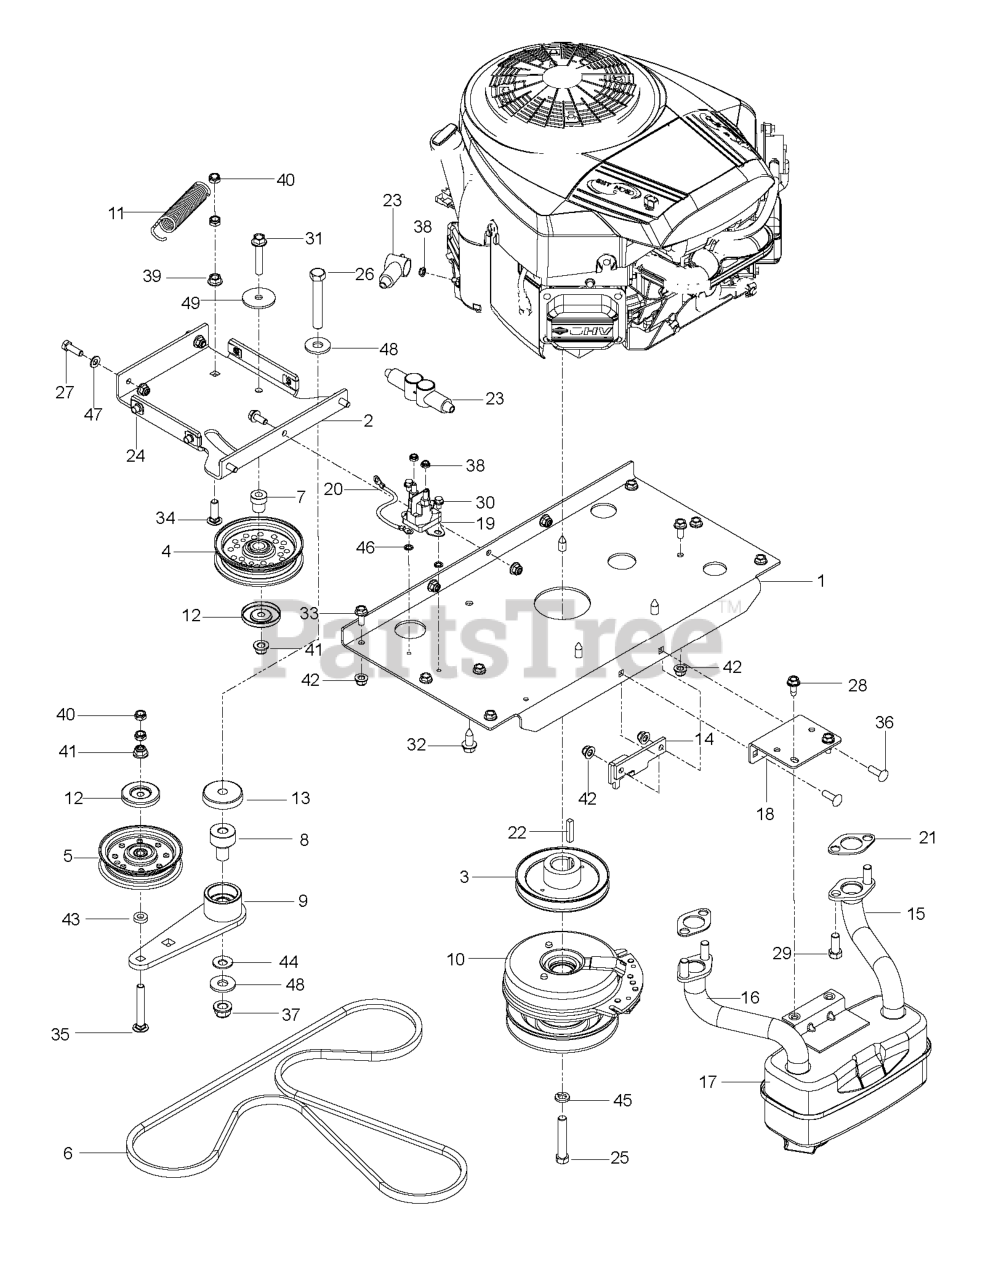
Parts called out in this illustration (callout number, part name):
1	PLATE, ENGINE W/DECALS
2	PLATE, IDLER, BLK
3	PULLEY, V, 1.125 BORE
4	IDLER PULLEY
5	FLAT IDLER PULLEY
6	BELT, HYDRO, 3400
7	PIVOT, IDLER
8	PIVOT, BEARING
9	ARM, IDLER, STEEL, W/BGS
10	CLUTCH 200 FT LB
11	SPRING, PUMP
12	DUST SHIELD
13	SHIELD, DUST
14	STOP, CLUTCH, BLACK
15	EXHAUST.TUBE.RH.B&S.TWIN.INTEK
16	EXHAUST.TUBE.LH.BS/TWIN
17	MUFFLER ASM TWIN
18	BRKT, MUFFLER, BLK
20	CABLE POSITIVE
21	GASKET.MUFFLER
22	KEY, 1/4 SQ X 1 1/4
24	U-CLIP 5/16-18 NUT RETAINER
25	CLUTCH BOLT7/16-20X2.5 GR596HR
26	HCS 1/2C X 3 1/4
27	HCS 5/16C X 1
28	BOLT 5/16-18 X 3/4
29	SCREW.SOCKET.HEAD.5/16-18
30	HWST 1/4C X 3/8
31	HHFS 3/8-16 X 2.0 GD 5
32	HHFS 3/8-16 X 1.0 THD FORMING
33	HHFS 5/16-18 X 3/4
34	RHSNB 3/8-16 X 1-1/4
35	RHSNB 3/8-16 X 2.75
36	RHSSNB 5/16C X 1.0
37	NUT, 1/2-13 HEX FLG NYLOC ZD
38	JAM NUT 1/4C (2 2 PW01)
39	NUT 3/8C WHIZ
40	NUT HEX 3/8-16 NYLON, THIN
41	NUT 3/8-16 HEX FLG NYLOC ZD
42	5/16-18 NYLOC FLANGE NUT
43	WASHER 3/8 X 3/4 X .187 TK
44	CONTACT BELLSPR 1/2
45	WASHER 7/16 LOCK
46	WASHER 1/4 INT TOOTH
47	FLAT WASHER 5/16 SAE
48	WASH USS FLAT 1/2
49	WASHER, 3/8 SPEC
